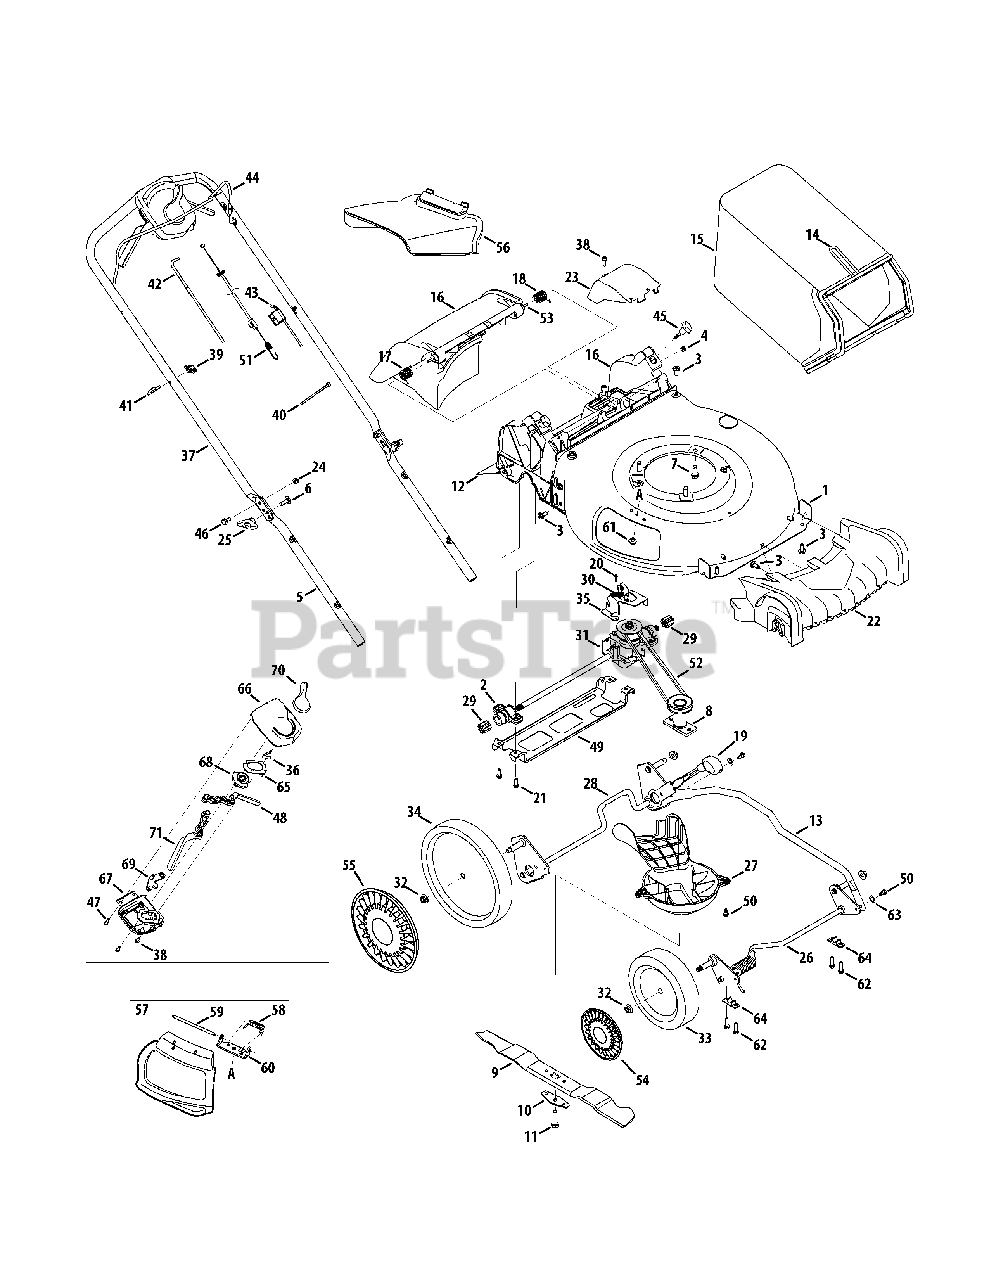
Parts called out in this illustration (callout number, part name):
1	Deck , 21" - Black
1	Deck , 21" - Green
2	Bearing Assembly
3	Screw, 5/16-14 x .750
4	Nut, Sq., 1/4-20
5	Lower Handle
6	Carriage Screw ,5/16-18
7	Screw, 3/8-16 x 1.00
8	Blade Adapter
9	Mulching Blade
10	Blade Bell Support
11	Screw, 3/8-24 x 1.50
12	Trailing Shield
13	Cross Bracket
14	Grass Catcher Frame
15	Grass Bag
15	Grass Bag (Yardman)
16	Rear Discharge Door Assembly
17	Torsion Spring - RH
18	Torsion Spring - LH
19	Adjustment Lever Knob
20	Torx Screw
21	Screw, 1/4-15 x 1.25
22	Front Cover
23	Transmission Cover
24	Nut, Flange Lock, 1/4-20
25	Wing Knob, Red
25	Wing Knob, Black
26	Front Axle Assembly
27	Engine Baffle
28	Rear Axle Assembly
29	Spur Gear, 9T
30	Exten. Spring, 2.405
31	Transmission Assembly
32	Flange Lock Nut, 3/8-16
33	Front Wheel
34	Rear Wheel
35	Transmission Bracket
36	Spring
37	Upper Handle
38	Screw, 1/4-15 x .750
40	Cable Tie
41	Rope Guide
42	Drive Cable
43	Control Cable
44	Blade Control
45	Wing Nut, Red
45	Wing Nut, Black
46	Sldr. Screw, .375 x .126 x 1/4-20
47	Scr., Shldr, 1/4-15 x .970
48	Control Lever LH
49	Rear Support Bracket
50	Scr., Shldr., 1/4-20 x .50
51	Speed Adjustment Cable
52	V-Belt
53	Pivot Rod
54	Hubcap, Grey
55	Hubcap, 11", Grey
56	Side Discharge Chute
57	Mulch Plug (Incl. 58-60)
58	Torsion Spring
59	Hinge Pin
60	Chute Deflector Bracket
61	Screw, 1/4-20 x .500
62	Screw, 1/4-15 x .750
63	Wash., Wave, .385 ID x .598 OD
64	Bushing, Lock, .505 Dia. X .62
65	Cable Adjust Plate
66	Upper Housing
67	Lower Housing
68	Speed Adjust Actuator
69	Drive Cable Actuator
70	Speed Select Lever
71	Control Lever RH
